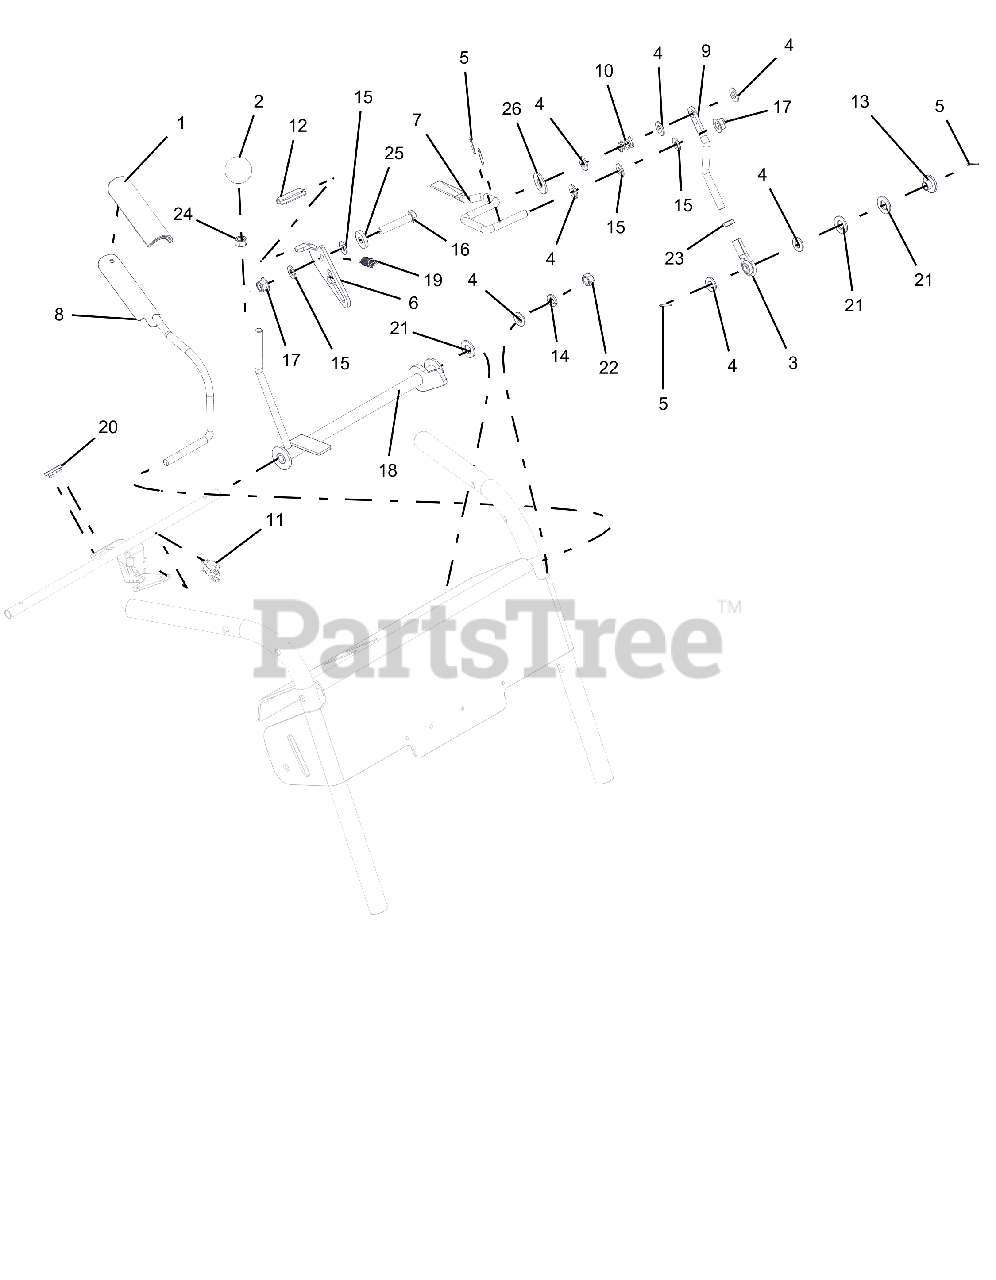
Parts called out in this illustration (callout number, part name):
1	GRIP, CLUTCH LEVER, LH AND RH
2	KNOB,BALL -BLACK 1.47" .375-16
3	ROD END, .38 RH
4	WSHR-FL-STL.406X.812X.065 YWZ
5	@PIN-CTR .09X.75 EXTPRSQCT YWZ
6	LATCH-LH THUMB
7	LEVER, HAND CONTROL LH
8	WLDMT, LEVER LH OP MY14-BLACK
9	ROD, STEERING LINK
10	SPRG, COMPRESSION
11	SPRG, EXTENSION
12	GRIP, THUMB LATCH
13	BSHG-FLG .385X.500X.875X.31
14	WSHR-LK .38X.094 REG YWZC
15	WSHR-FL-NYL .375X.75X.060
16	BLT-HEX .38-16X2.00 GR5 YWZC
17	NUT-LK-NYL-FLG .38-16 YWZC
18	WELDMENT, LH LEVER
19	SG-TENS .041X.500X1.750
20	BUMPER GROMMET .125 X .25 REV
21	WSHR-FL-NYL .518X1.00X.08
22	NUT-HEX .375-24 YWZC
23	NUT-JAM .375-24 YWZC
24	NUT-HEX .38-16 YWZC
25	WSHR-FL-STL .406X1.00X.188 YWZC
26	WSHR-FL-STL..50X1.25X.083 YWZ
